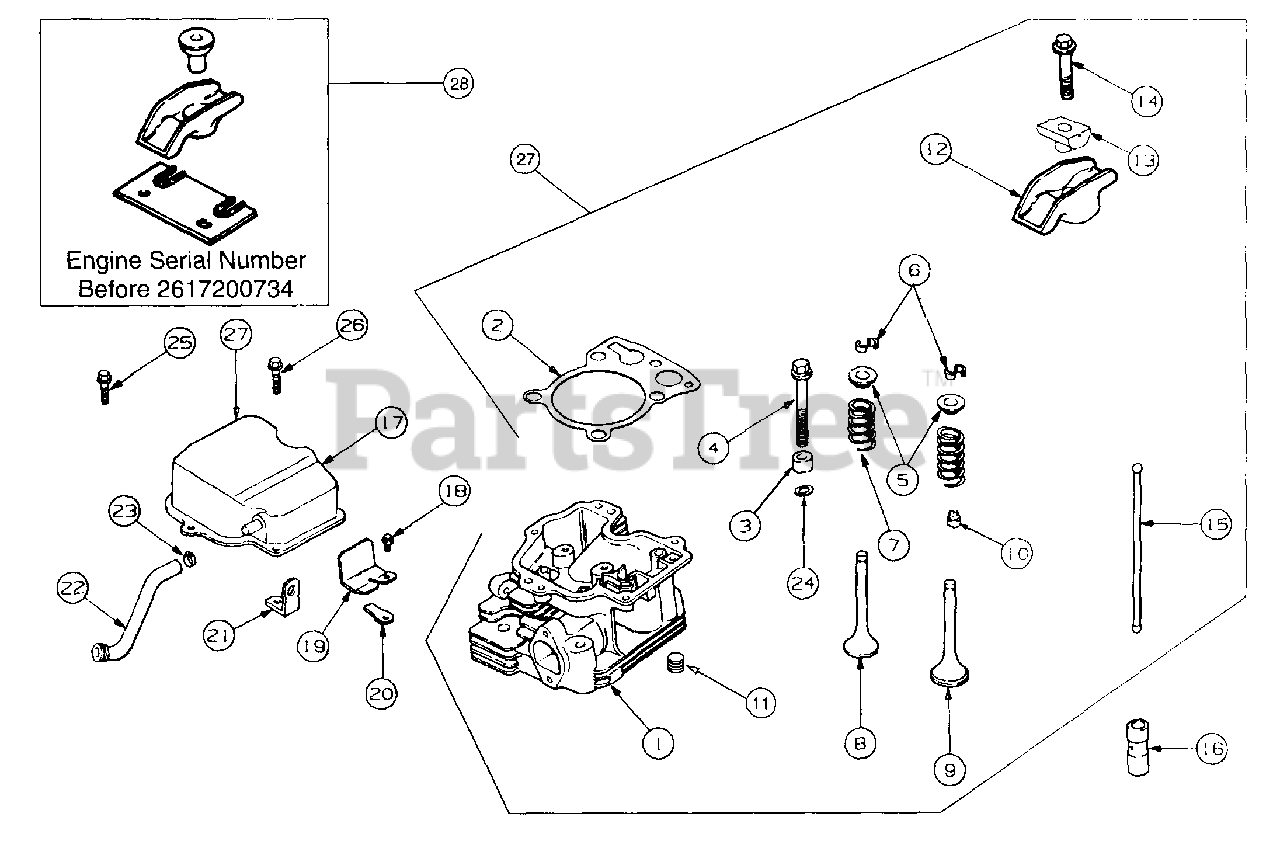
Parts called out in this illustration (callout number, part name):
1	Cylinder Head
2	Gasket, Cylinder Head
3	Spacer, Head Bolt, Exhaust Port
4	Screw, Cylinder Head, M10 x 1.5 x 81
5	Cap, Valve Spring
6	Kit, Retainer
7	Spring, Valve
8	Valve, Exhaust, Std
9	Valve, Intake, Std
10	Seal, Valve Stem
11	Plug, Allen Hd. 1/8" Pipe
13	Pivot, Rocker Arm
14	Screw, Pivot Rocker M6 x 1.0 x 34
15	Rod, Push
16	Lifter, Valve
17	Cover, Valve w/Nipple
18	Screw, Breather Reed Ret. M5 x 0.8 x 10
19	Retainer, Breather Reed
20	Reed, Breather
21	Strap, Lifting
22	Hose, Breather
23	Clamp, Hose
24	Washer, Flat
25	Screw, Hex Flange, M6 x 1.0 x 20
26	Screw, Valve Cover M6 x 1.0 x 25
27	Kit, Cylinder Head
28	Upgrade to Current Rocker Arm Assy
